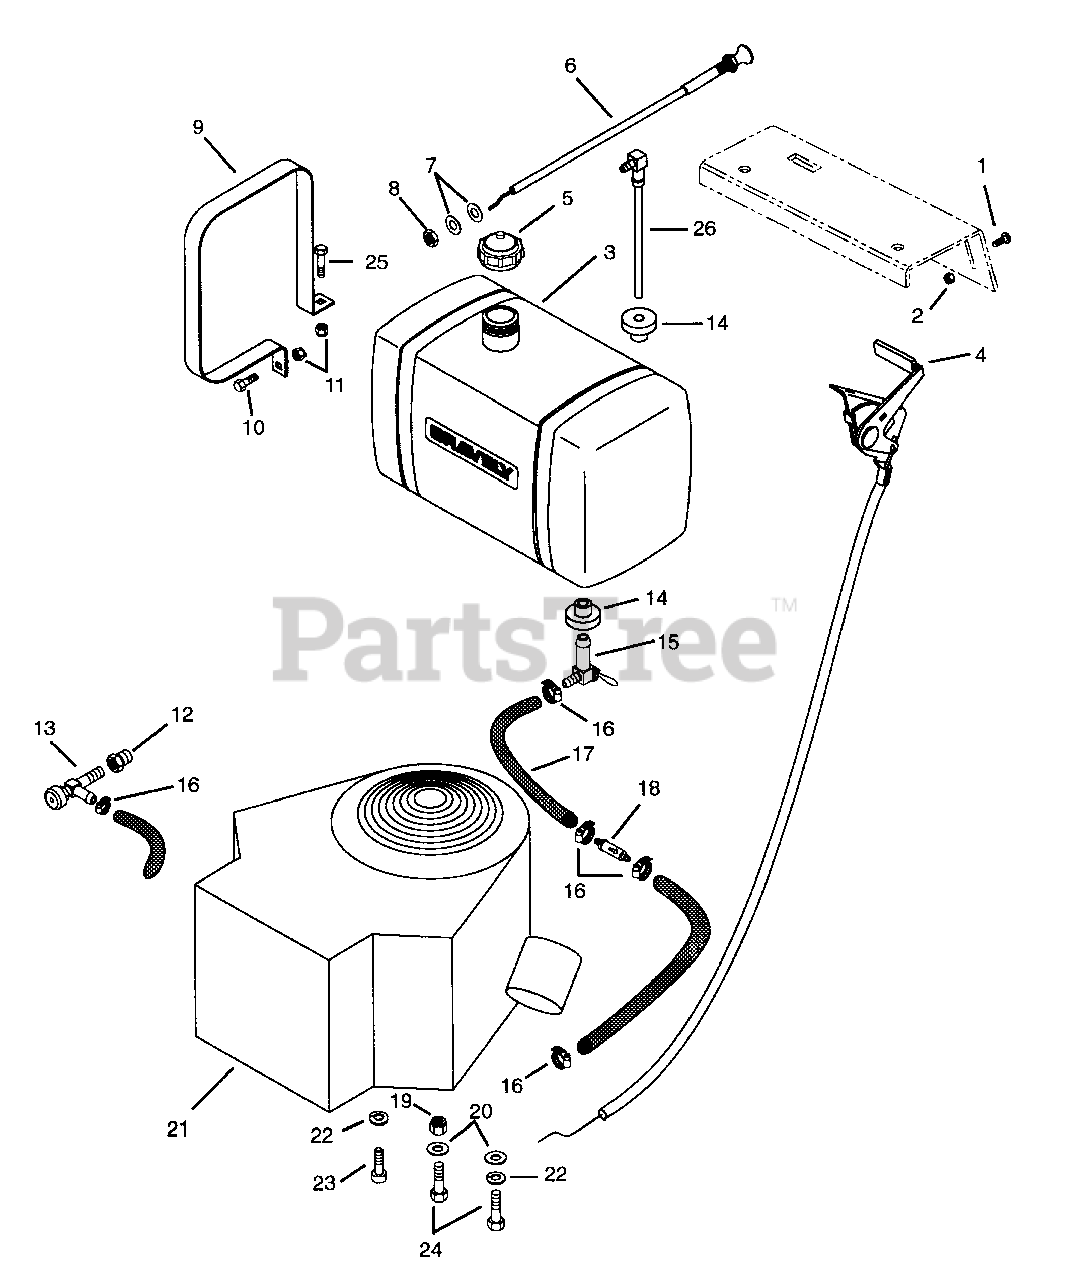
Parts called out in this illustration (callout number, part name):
1	Screw-Machine 10-32 x .50
2	Nut-Locking 10-32
3	Tank, Fuel Gravely PRO
4	Assembly, Throttle Control
5	Cap, Fuel Tank
6	Control, Choke
7	Washer-Flat-Steel .406 x .812 x .065
8	Nut-Jam .375-24
9	Strap, Fuel Tank
10	Bolt-Hex .25-20 x .63
11	Nut-Locking-Nylon .250-20
12	Adapter, Oil Drain
13	Cock, Oil Drain
15	Valve, Ball Shut Off
16	Hose Clamp
17	Gas Line
18	Filter, Fuel
19	Nut-Locking-Nylon .312-18
20	Washer-Flat-Steel .344 x .688 x .065
21	Engine, 16 H.P. Briggs & Stratton
22	Washer-Lock .313 x .078
23	Bolt-Hex M8 x 1.25 x 30mm
24	Bolt-Hex .31-18 x 1.50
25	Bolt-Hex .25-20 x 1.00 Grade 5
26	Fitting, Tank
